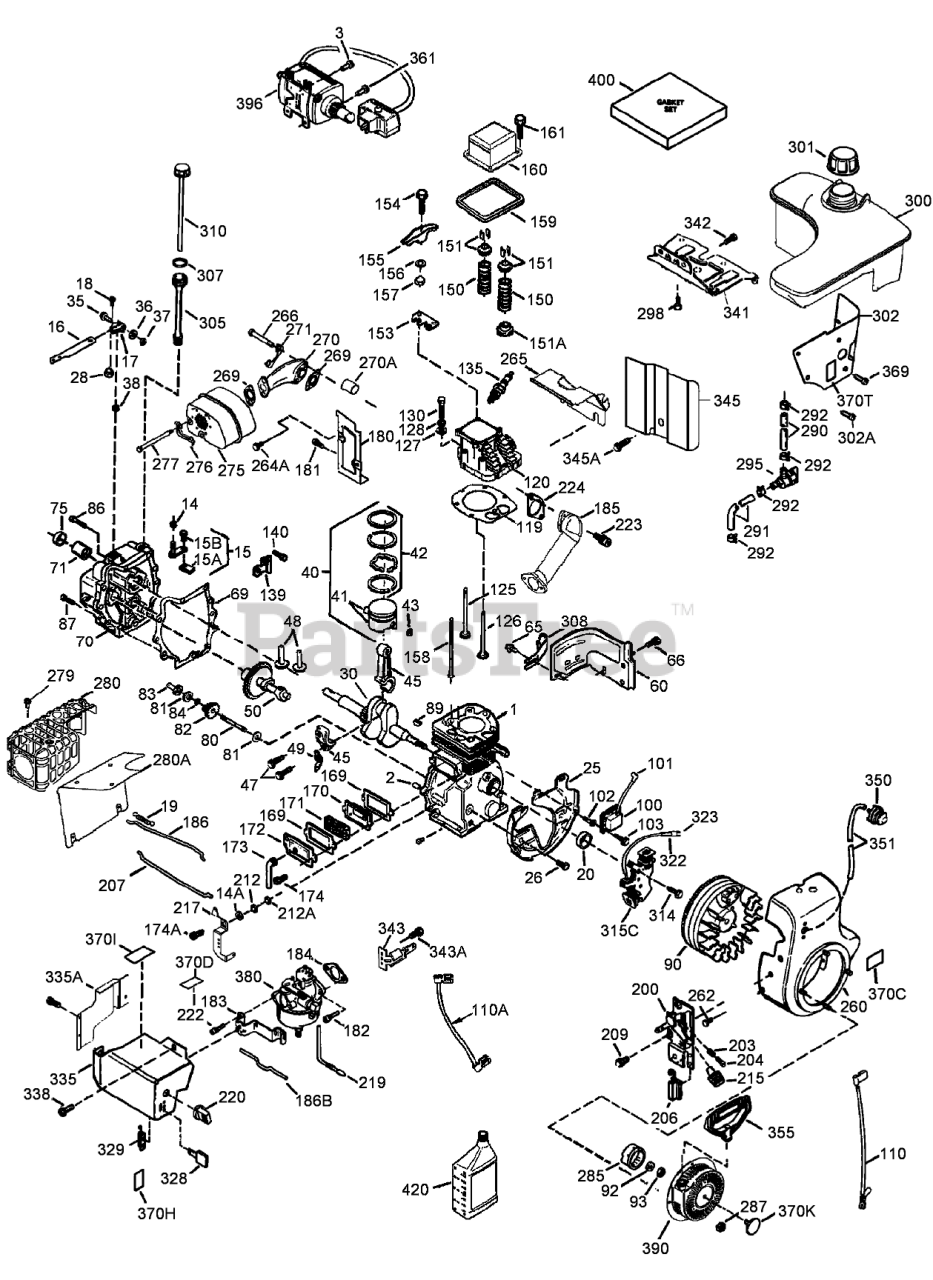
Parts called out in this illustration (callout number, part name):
185	Pipe-Intake
186	Link-Governor
186B	Spring-Choke
200	Bracket-Control (Includes 203, 204, 206)
203	Spring-Compression
204	Screw (T-10, 5-40x7/16)
206	Terminal
207	Link-Throttle
209	Screw (10-32 x 1/2)
212	Bushing
212A	Bushing
215	Knob-Control
217	Lever-Bellcrank
219	Rod-Choke
220	Knob-Control
222	Screw (10-32 x 1/2)
223	Screw (T-30, 5/16-18 X 7/8)
224	Gasket-Pipe
260	Housing-Blower
262	Screw (5/16-18x9/16)
264A	Screw (1/4-20 X 5/8)
265	Cover-Head, Cylinder
266	Screw (5/16-18 X 1-9/32)
269	Gasket-Manifold, Exhaust
270	Manifold, Exhaust
270A	Liner-Port, Exhaust
271	Plate-Locking
275	Muffler
276	Plate-Locking
277	Screw (5/16-18 X 4-1/2)
279	Screw
280	Shield-Heat
280A	Baffle-Restrictor, Air
285	Cup-Starter
287	Nut and Lock Washer (1/4-28)
290	Line-Fuel
291	Line-Fuel (8.62)
292	Clamp-Line, Fuel
295	Valve-Shut Off, Fuel (Includes 292)
298	Screw (1/4-15x7/8)
300	Tank-Fuel (Includs 292, 301)
301	Cap-Fuel (Black) (1-1/2 I D)
302	Extension-Tank, Fuel
302A	Screw (10-32 x 1/2)
305	Tube-Fill, Oil
307	O-Ring
308	Clip-Tube, Fill
310	Dipstick
314	Screw (1/4-20 x 3/4)
315C	Coil-Alternator, 18 Watt (Includes 322, 323)
322	Body-Connector
323	Terminal
328	Key-Ignition
329	Terminal
335	Cover-Carburetor, Front
335A	Cover-Carburetor
338	Screw (10-32 x 1/2)
341	Bracket-Tank, Fuel
342	Switch-Pressure, Oil
343	Bracket-Switch, Key (Includes 343A)
343A	Screw (8-32 x 23/64)
345	Baffle-Heat
345A	Screw (10-32 x 1/2)
350	Primer ASM
351	Line-Primer
355	Handle-Starter, Mitten Grip
361	Screw (T-30, 1/4-20x15/32)
369	Screw (12-16 x 5/8)
370C	Decal-Primer, International Symbol
370D	Decal-Instruction
370H	Decal-Choke
370I	Decal-Warning (Bilingual)
370K	Decal-Tecumseh Logo for Top of Recoil Starter
370T	Decal-Starter, Electric
380	Carburetor (Includes 184)
390	Starter-Rewind
396	Starter-Electric (110 Volt)
400	Gasket Set (Includes 69, 119, 159, 169, 184, 224, 269)
420	Oil-Engine, S A E 5W30
